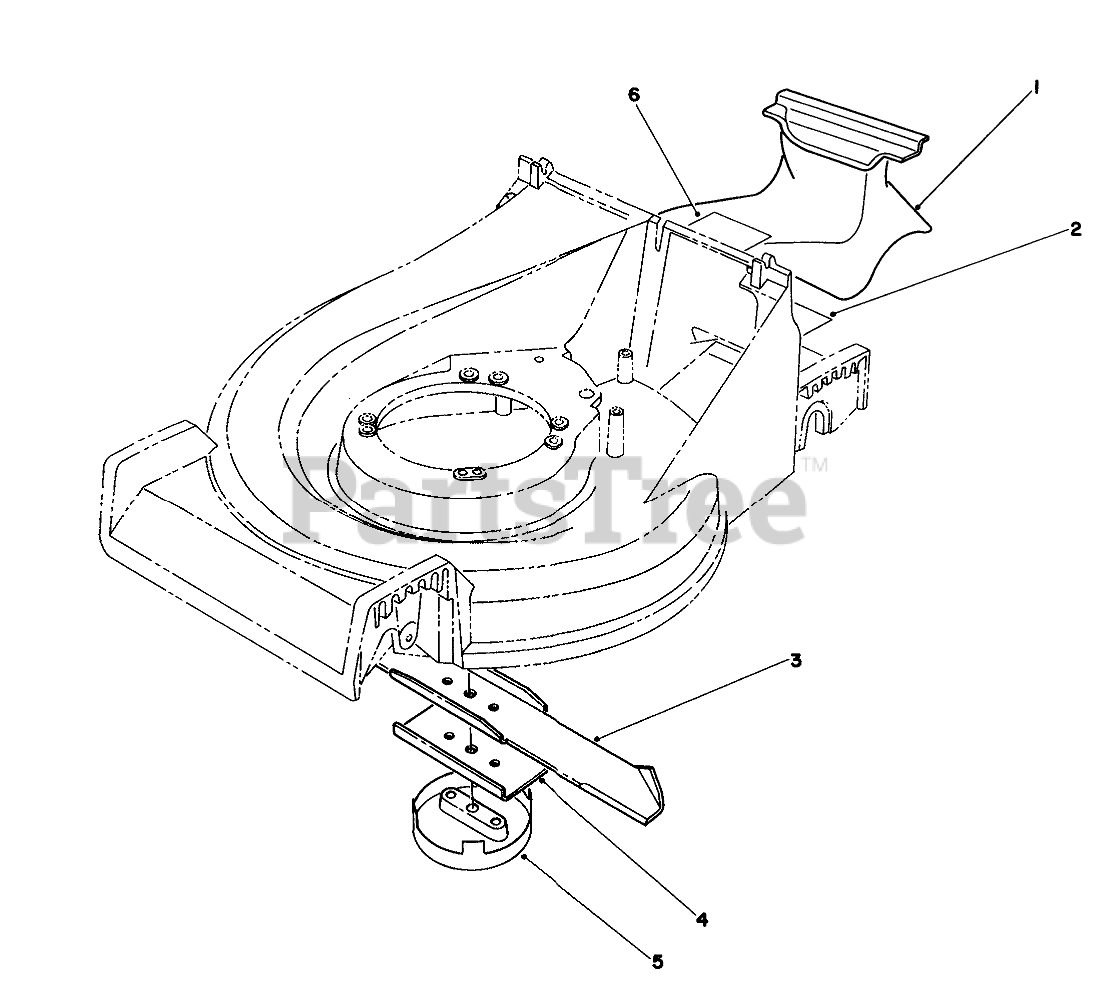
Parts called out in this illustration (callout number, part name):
1	RECYCLER PLUG
2	DECAL - MULCHER KIT
3	BLADE-21in
4	Stiffener
5	CUP-SCALP, ANTI
6	DECAL - FRENCH
